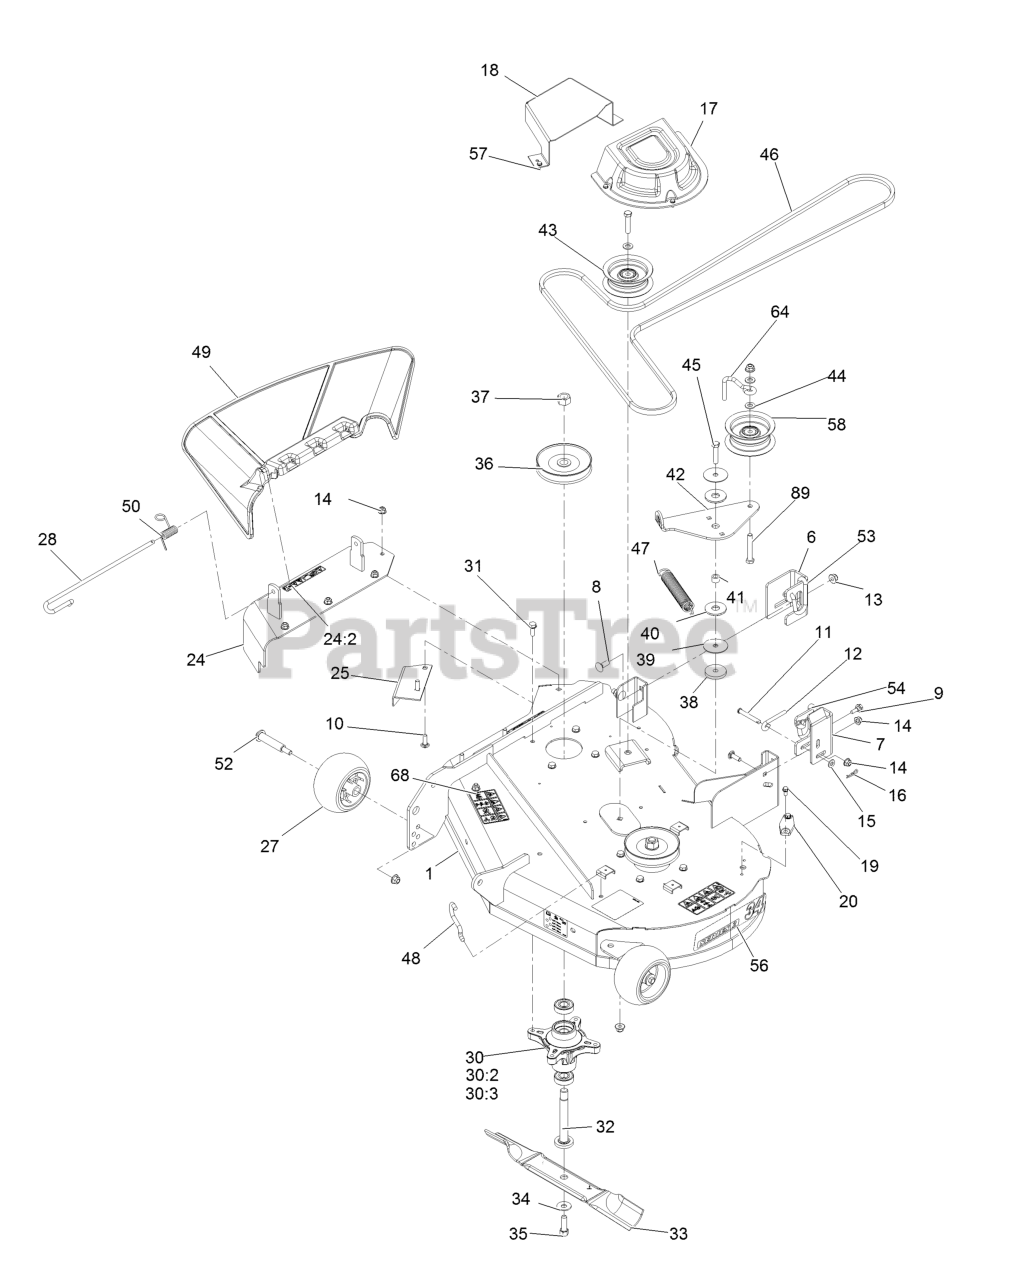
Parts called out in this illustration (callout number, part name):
1	34 INCH DECK AND DECAL AS
6	BRACKET-HANGER, RH
7	BRACKET-HANGER, LH
8	BOLT-CARR
9	SCREW-SHOULDER,HWH
10	SCREW-CARR
11	PIN-CLEVIS
12	ROD-LEVEL, DECK
13	NUT-HF, NI
14	NUT-HF, NI
15	WASHER-PLAIN
16	PIN-COTTER
17	COVER-BELT
18	COVER-DECK BELT
19	SCREW-HWH
20	COVER-WASHOUT PORT
24	COVER ASM W/DECAL
24:2	DECAL-DANGER
25	BAFFLE-CUTOFF
27	ROLLER-SCALP, ANTI
28	PIN-CHUTE
30	SPINDLE ASM
30:3	BEARING-BALL
31	SCREW-TAPTITE
32	SHAFT-SPINDLE
33	BLADE-HI LIFT
34	WASHER-BELLEVILLE
35	SCREW-HH
36	PULLEY ASM
37	NUT-HEX
38	WASHER-PLAIN
40	WASHER-FRICTION, COMPOSIT
42	ARM-IDLER
44	WASHER-FLAT
45	SCREW-HH
46	BELT-V
47	SPRING-EXTENSION
48	HOOK-RETURN, SPRING
49	DEFLECTOR-DISCHARGE
50	SPRING-TORSION
52	BOLT-SHOULDER
53	LINK-RETENTION, DECK (RH)
54	LINK-RETENTION, DECK (LH)
56	Decal - Series 2 34
57	SCREW-TAPTITE
64	GUIDE-IDLER, BELT
68	SCREW-HH
89	BOLT-CARR
